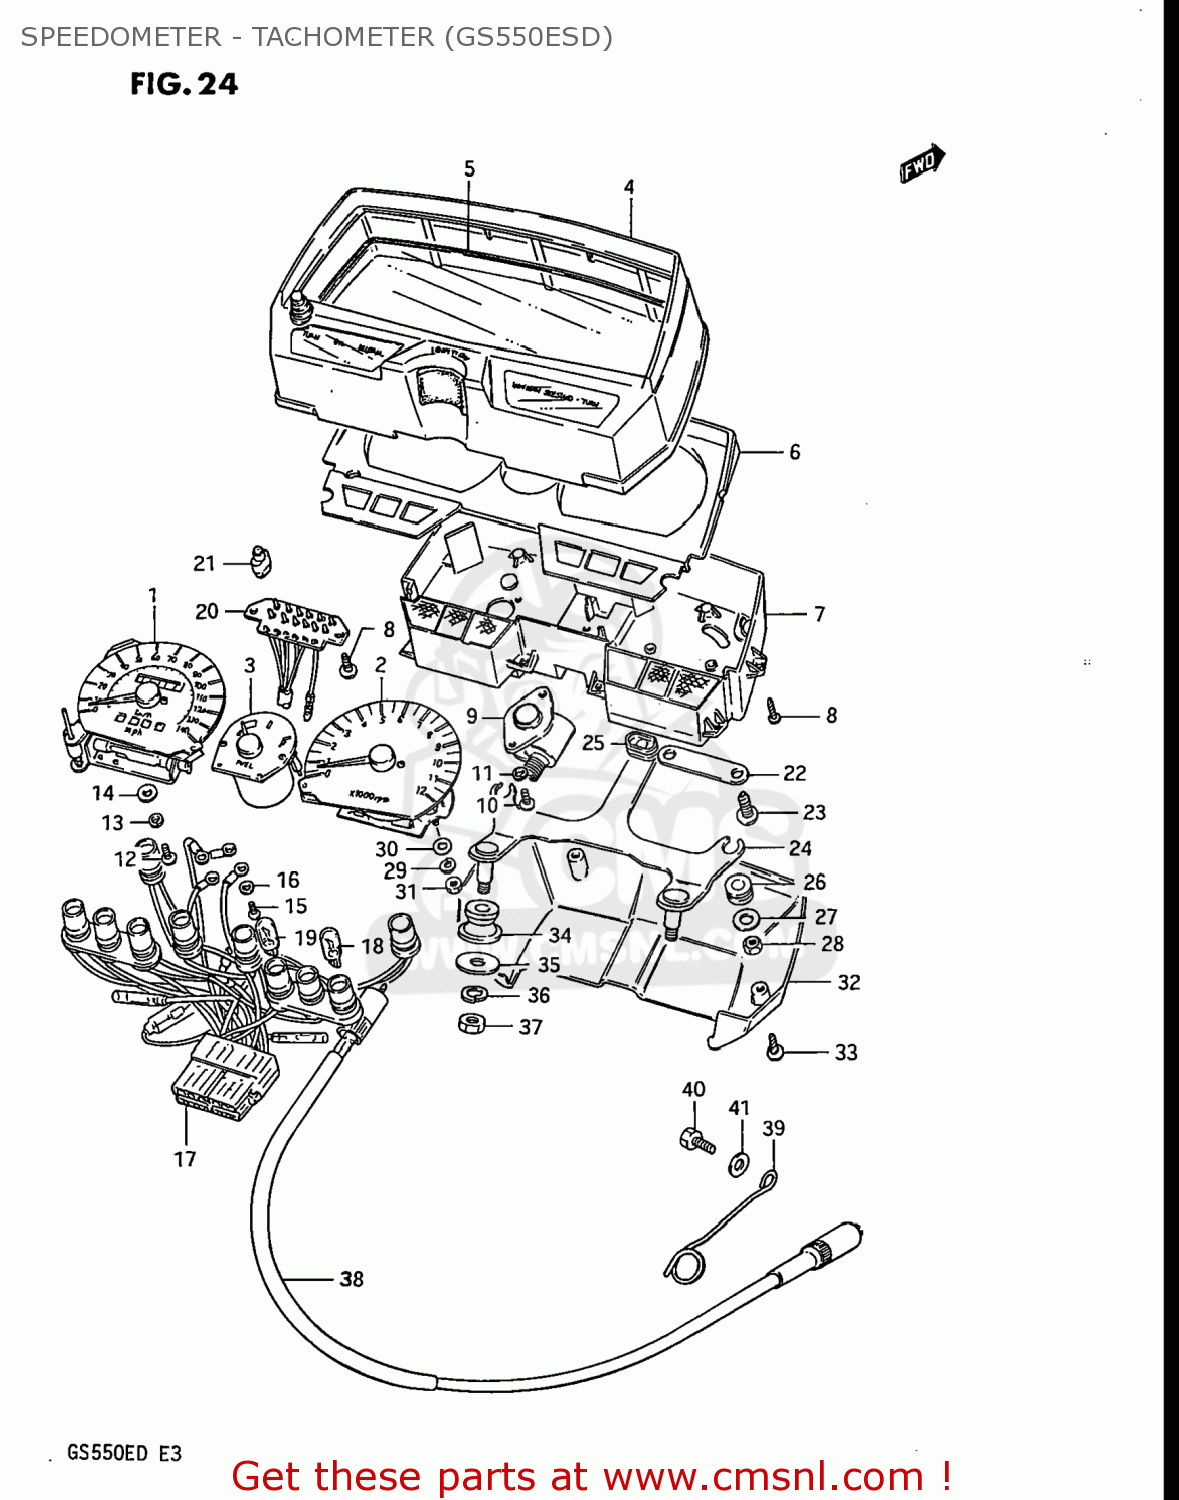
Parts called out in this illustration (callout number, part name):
1	SPEEDOMETER
2	TACHOMETER
3	METER,FUEL
4	HOOD,METER
5	GLASS,SPEEDOMETER
6	PLATE,METER WINDOW
7	CASE,METER,INNER
8	SCREW,GEAR INDICATOR
9	BOX,GEAR
10	SCREW 4X10
11	LOCK WASHER
12	SCREW
13	LOCK WASHER
14	WASHER
15	SCREW
16	WASHER
17	SOCKET,METER
18	BULB(12V3.4W,T10,BF175-01450A)
19	BULB(12V1.7W,T10,WB121)
20	SOCKET,GEAR INDICATOR
21	BULB(14V1.12W)
22	PLATE,COUPLER
23	SCREW
24	BRACKET,METER
25	CUSHION,METER
26	CUSHION,METER
27	WASHER,METER
28	NUT
29	LOCK WASHER
30	WASHER,SPEEDOMETER
31	NUT
32	COVER,METER,UNDER
33	SCREW
34	CUSHION,METER BRACKET
35	WASHER (8.5X20X1.6)
36	LOCK WASHER
37	NUT
38	CABLE ASSEMBLY,SPEEDOMETER
39	CLAMP,SPEEDOMETER CABLE
40	BOLT, UPPER
41	WASHER
